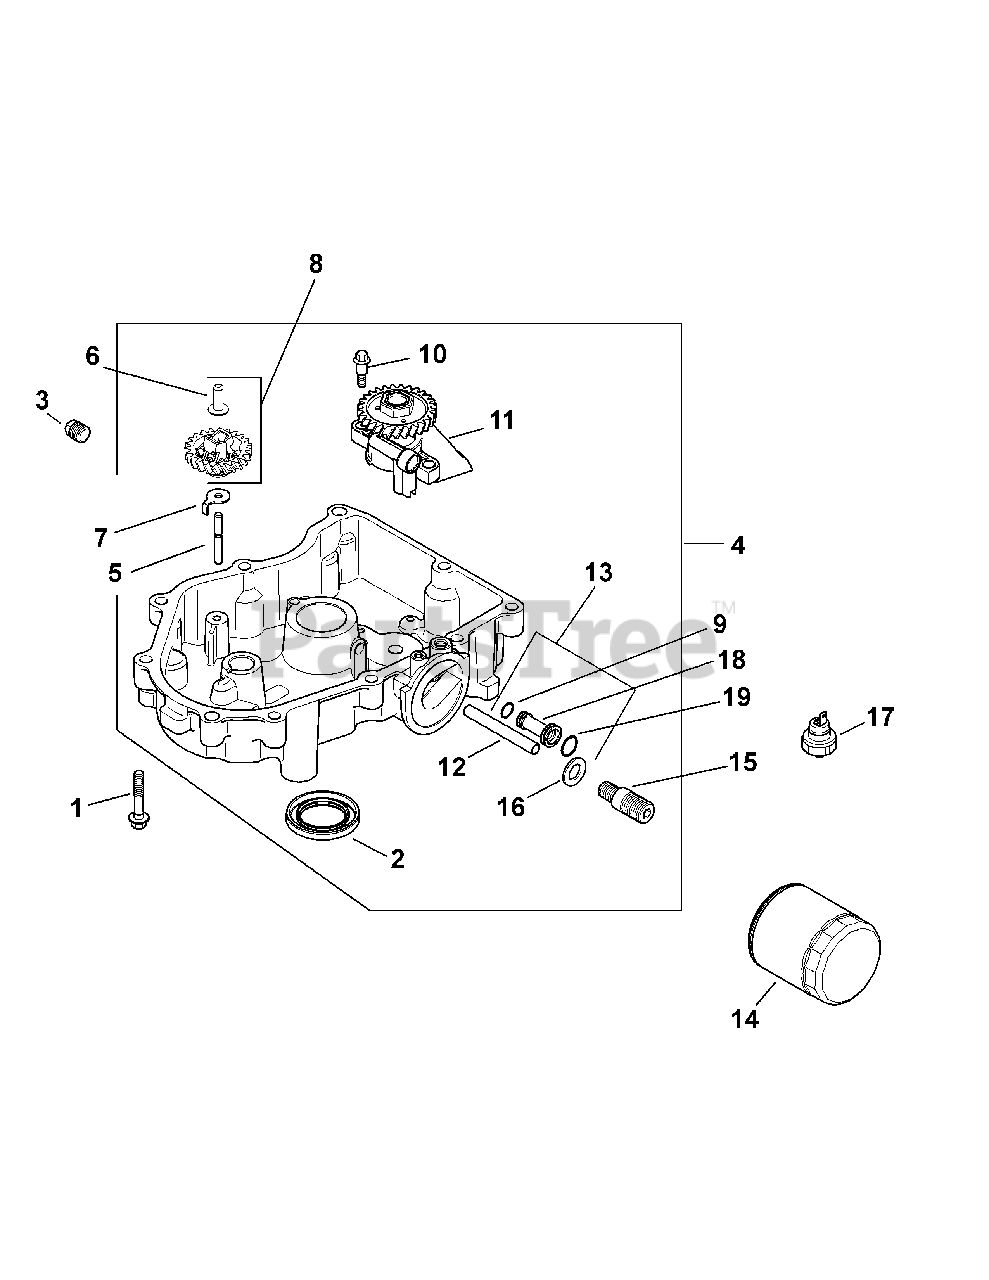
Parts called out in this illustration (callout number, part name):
1	Flange Screw, M8 x 1.25 x 45
2	Oil Seal, 2.38 x 1.45
3	Square Head Pipe Plug, 3/8
4	Oil Pan Assembly
5	Governor Gear Shaft
6	Governor Regulating Pin
8	Governor Gear Kit
9	Oil Pick-Up O-Ring
11	Oil Pump Assembly
12	Oil Feed Tube (Filter to Oil Pan)
13	Oil Feed Tube Assembly
15	Oil Filter Nipple
17	Oil Pressure Switch
18	Oil Feed Tube
